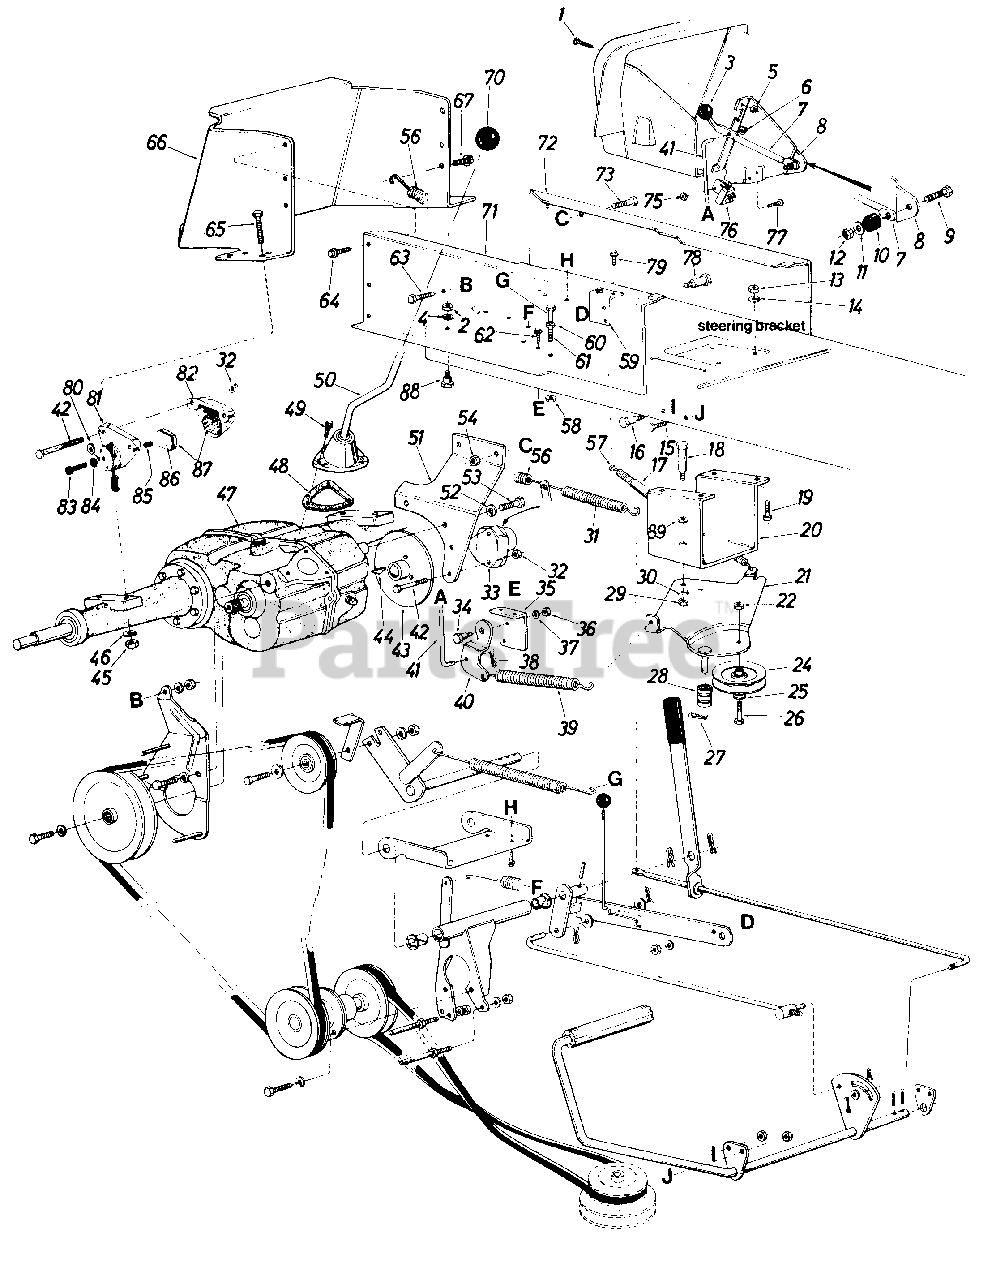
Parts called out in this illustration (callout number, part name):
1	Truss Mach. Scr. 1/4-20 x .50" Lg.
2	Hex Nut 1/4-20 Thd.
3	Knob-Blade Clutch
4	L-Wash. 1/4 I.D.
5	Hex Sems Nut 1/4-20 Thd.
6	Push Cap 1/4" Rod
7	Blade Clutch Lever
8	Deck Clutch Control Brkt.
9	Hex Scr. 1/4-20 x 1.25" Lg.
10	Rubber Wash. .330 I.D. x .87
11	Fl-Wash 1/4" I.D. x .75" O.D. x .057
12	Hex Cent. L-Nut 1/4-20 Thd.
13	Hex Nut 5/16-18 Thd.
14	L-Wash. 5/16" Scr.
15	Hex Scr. 3/8-16 x .62" Lg.
16	Shld. Scr. 1/2" Dia. x .335 Lg. 3/8-16
17	Convoluted Conduit .50 I.D. x 4" Lg.
18	Shld. Scr. 7/16 Dia. x .16" 5/1 6-1 8
19	Hex Scr. 5/16-18 x 1.00" Lg.
20	Idler Mtg. Brkt.-Deck
21	Idler Brkt. Ass'y.
22	Hex L-Nut 3/8-16 Thd.
24	4"-"V" Idler Pulley
25	Fl-Wash. 3/8" I.D.
26	Hex Scr. 3/8-16 x 1.25" Lg.
27	Hairpin Cotter 5/16" Rod
28	Spacer
29	Hex Nut 5/16-18 Thd.*
30	L-Wash. 5/16" Scr.
31	Ext. Spring-Brake Rod
32	Hex Cent. L-Nut 3/8-16 Thd.
33	Disc Brake Caliper Ass'y.
34	Shld. Scr. 7/16" Dia. x .16" Lg. 5/16-18
35	Parking Brake Cam Mtg. Brkt.
36	Hex Nut 5/16-18 Thd.
37	L-Wash. 5/16" Scr.
38	Hairpin Cotter 5/16" Dia.
39	Ext. Spring-Deck Control
40	Deck Control Pivot Brkt.
41	Deck Control Rod
42	Hex Scr. 3/8-16 x 2.50" Lg.
43	Hub & Disc Ass'y.
44	Hi-Pro Key 3/16 x 314" Lg.
45	Hex Nut 3/8-16 Thd.
46	L-Wash. 3/8" Scr.
47	Transaxle
51	Transaxle Support
52	L-Wash. 3/8" Scr.
53	Hex Scr. 3/8-16 x .75" Lg.
54	Hex L-Nut 3/8-16 Thd.
56	Ext. Spring-Brake Return
57	Ext. Spring-Deck Idler Return
58	Hex L-Nut 5/16-18 Thd.
59	Parking Brake Cam Mtg. Brkt.
60	Hex Nut 5/16-18 Thd.
61	Hex Scr. 5/16-18 x 1.50" Lg.
62	Hex Thd. Rolling Scr. 1/4-20 x.50" Lg.
63	Hex Scr. 3/8-16 x .75" Lg.
64	Hex AB-Tap Scr. 5/16 x .75" Lg.
65	Hex Scr. 3/8-16 x 1.50" Lg.
66	Hitch Plate
67	Hex Thd. Rolling Scr. 5/16-24 x .75" Lg.
70	Knob-Transaxle
71	Side Panel Upper Frame-R.H.
72	Side Panel Upper Frame-L.H.
73	Hex Scr. 3/8-16 x .75" Lg.
75	Hex Nut #10-24 Thd.
76	Safety Switch
77	Truss Mach. Scr. #10-24 x .50" Lg.
78	Shld. Scr. 7/16" Dia. x .16" Lg. 5/16-18
79	Hex Thd. Rolling Scr. 1/4-20 x.50" Lg.
81	Housing with Lever & Pin
83	Pin, Adjuster
84	Nut
85	Pin, Actuator
86	Backing Plate
87	Lining
88	Shld. Bolt .375" Dia. x .180" Lg. 1/4-20 Thd.
89	Wave Washer
